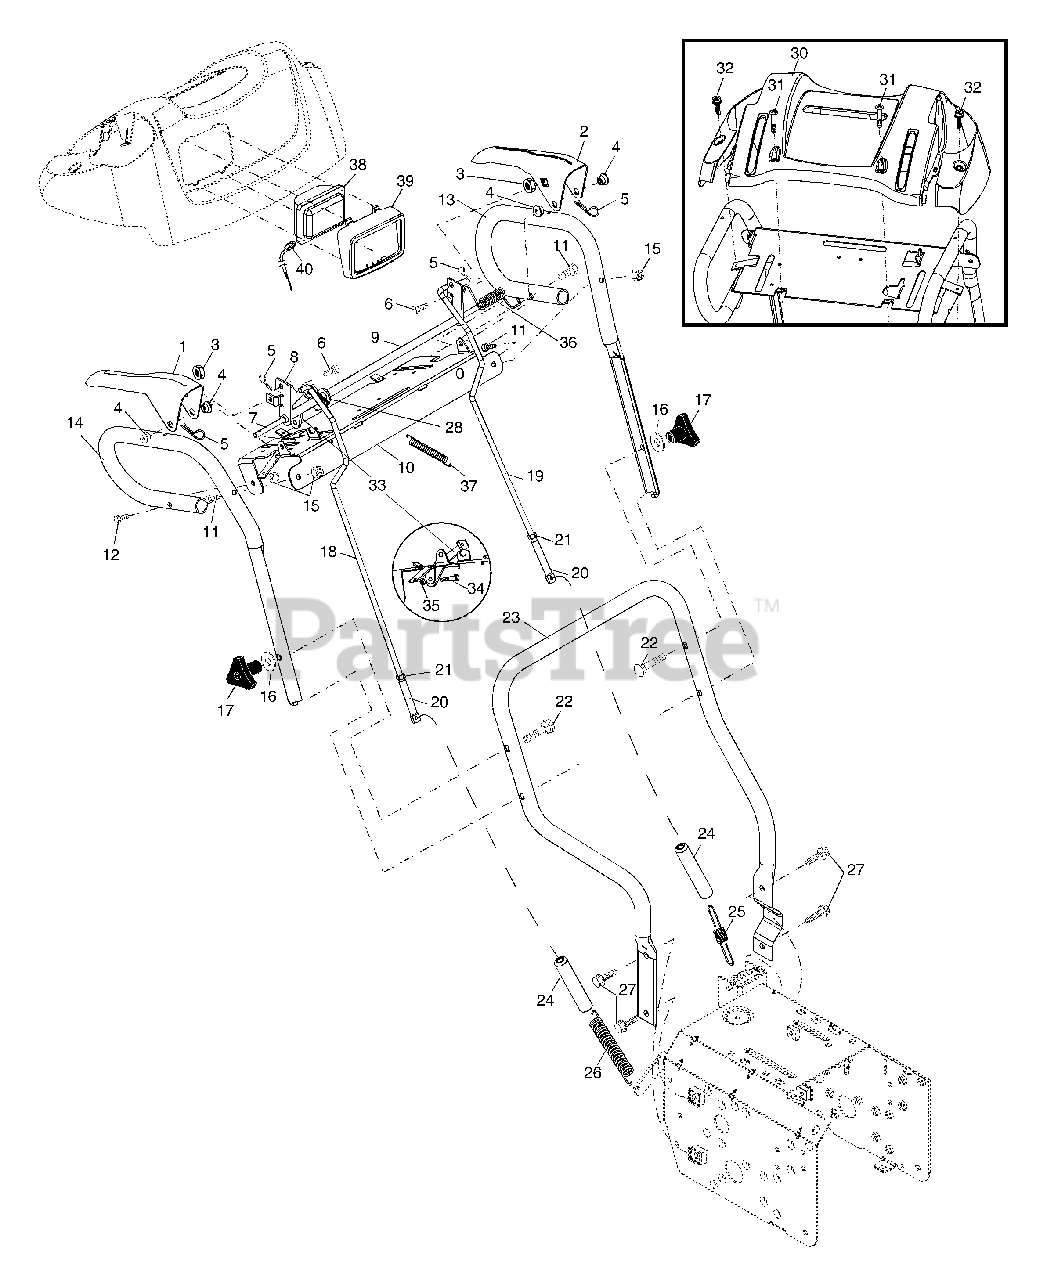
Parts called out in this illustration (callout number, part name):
1	Lever, Auger Control, RH
2	Lever, Traction Drive Control, LH
3	Nut, Cage 1/4-20
4	Bushing, Flange
5	Retainer, Hairpin
6	Screw, Hex Head 1/4-20 x 3/4
7	Rod, Interlock
8	Tube Assembly, Interlock, RH
9	Tube Assembly, Interlock, LH
10	Panel, Control
11	Screw, Hex Head 5/16-18 x 1-1/2
12	Screw, Hex Head 5/16-18 x 1-3/4
13	Handle Tube, LH
14	Handle Tube, RH
15	Nut, Lock 5/16-18
16	Washer, Flat 3/8
17	Knob, Handle
18	Rod, Auger Control
19	Rod, Traction Control
20	End, Control Rod
21	Nut, Hex, Jam 5/16-18
22	Bolt, Carriage 3/8-16 x 2-1/4
23	Handle Tube, Lower
24	Sleeve, Spring
25	Spring, Traction Drive
26	Spring, Auger Control
27	Screw, Hex Head 3/8-16 x 1
28	Clip, Panel
30	Console, Panel
31	Screw, Hex Head, Tapping #10-24 x 1-1/4
32	Screw, Hex Head, Tapping #10-24 x 1/2
33	Latch, Interlock
34	Bolt, Shoulder
35	Nut, Lock 1/4-20
36	Spring, Torsion
37	Spring, Interlock
38	Headlight, Halogen
39	Bezel, Headlight
40	Harness, Headlight (Halogen)
